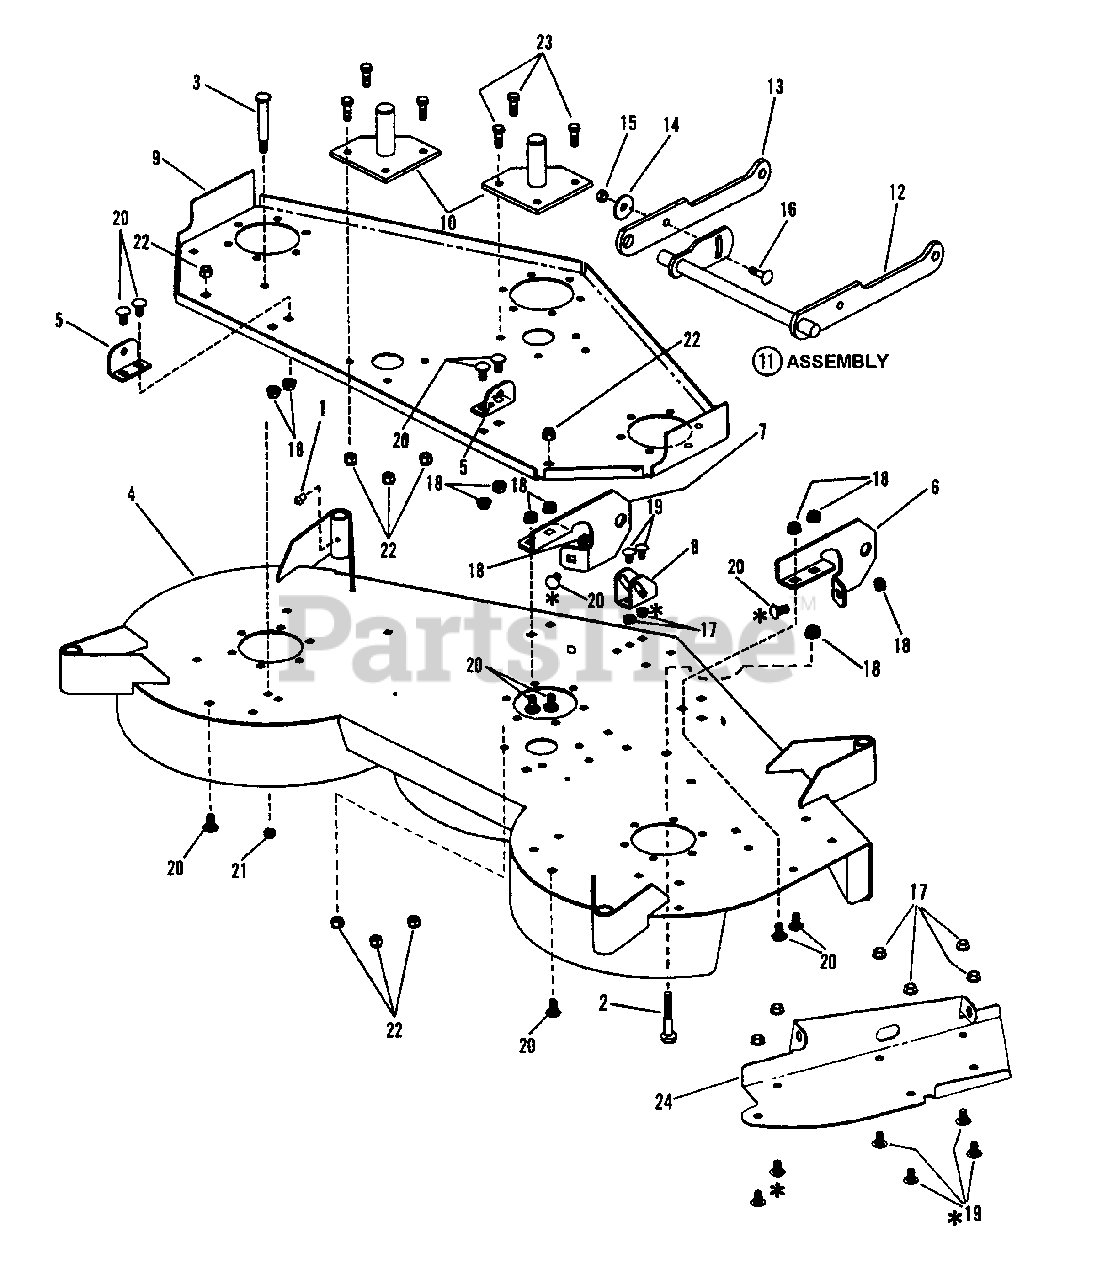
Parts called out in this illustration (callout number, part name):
1	LUBE FITTING, Straight (press-fit for .187 dia. Hole)
2	SCREW, 3/8-16 x 1-1/4" Hex Head Cap, Grade 5
3	BOLT, Gage Wheel
4	WELDMENT, Deck
5	BRACKET, Rear Lift- 48" Deck
6	BRACKET, Front Hanger- R.H.
7	BRACKET, Front Hanger- L.H.
8	BRACKET, Front Hanger- 48" Deck
9	STIFFENER, 48" Deck
10	WELDMENT, Idler Pivot
11	ASSEMBLY, Front Lift Arm- 97 Model Year
12	WELDMENT, Front Lift Arm
13	ARM, Lift
14	WASHER, Cone 3/8" I.D.
15	NUT, 3/8-16 Hex
16	BOLT, 3/8-16 x 1-1/4", Grade 5
17	NUT, 5/16-18 Hex Flange Lock, Grade 5
18	NUT, 3/8-16 Hex Flange Lock
19	BOLT, 5/16-18 x 5/8" Short Neck Carriage, Grade 5
20	BOLT, 3/8-16 x 3/4" Short Neck Carriage, Grade 2
21	NUT, 5/16-18 Hex Nyloc
22	NUT, 3/8-16 Hex Nyloc
23	SCREW, 3/8-16 x 1" Hex Head Cap, Grade 5
24	BRACKET, Hinge
